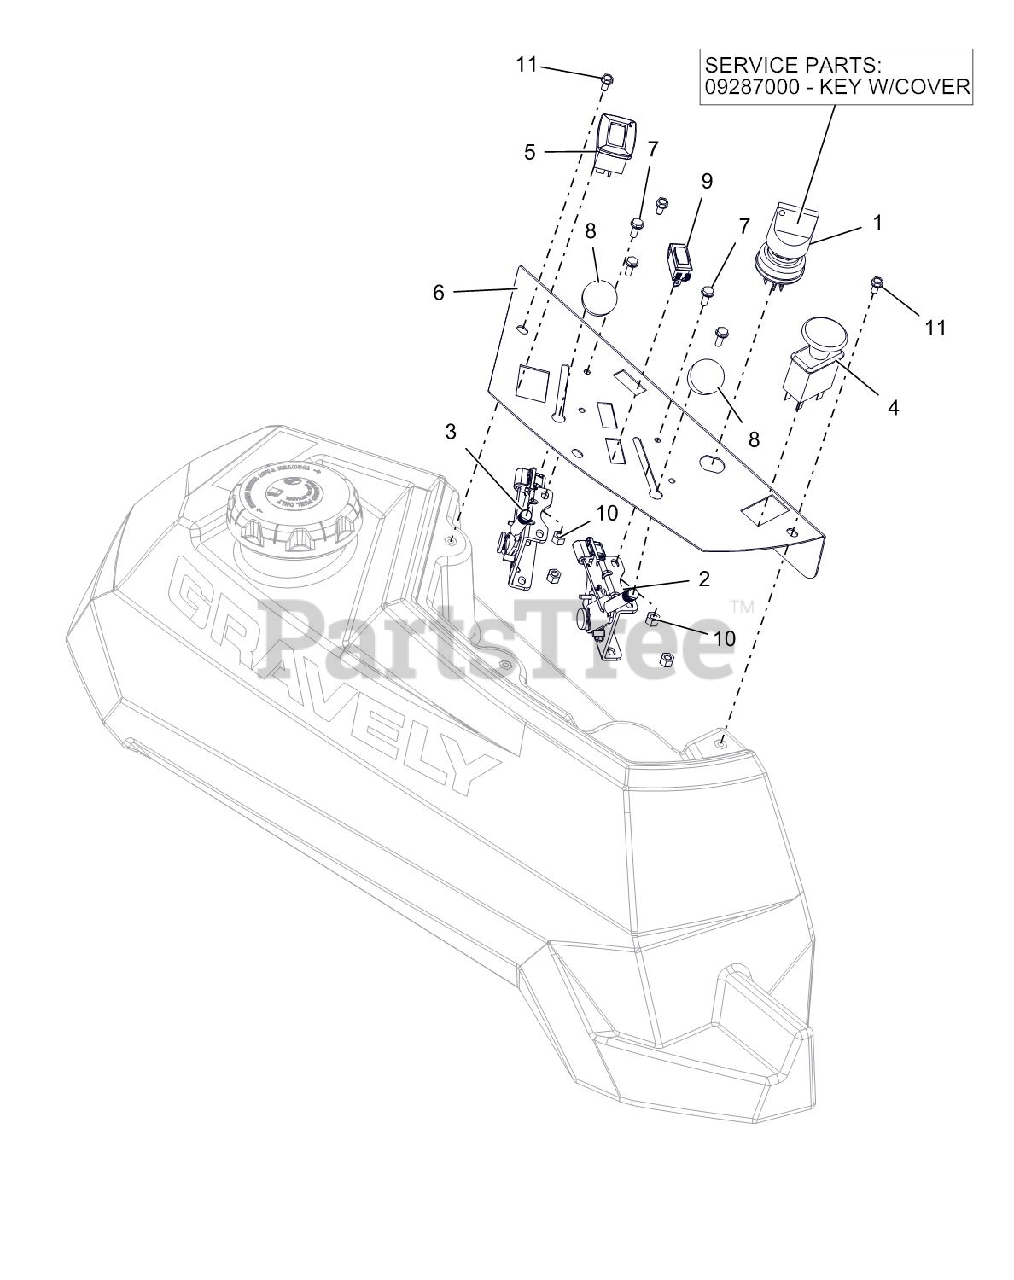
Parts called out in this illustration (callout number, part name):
1	KEY, W/ SHIELD
1	SWITCH, IGNITION
2	CABLE, PRO-CTRL 35.50"
3	CABLE, PRO-CONTROL 31.50"
4	SWITCH, CLUTCH
5	METER, HOUR W/MAINTENANCE
6	PT CONTROL PANEL - RED
7	@SCR-MCH 10-24X.50 HWH YWZC
8	KNOB-CONTROL-BLACK .38-16X.50
9	LIGHT,INDICATOR
10	@NUT-LK-NYL 10-24 W/INSRT YWZC
11	SCR-MCH 10-24X.38 HWHSTAINLESS
